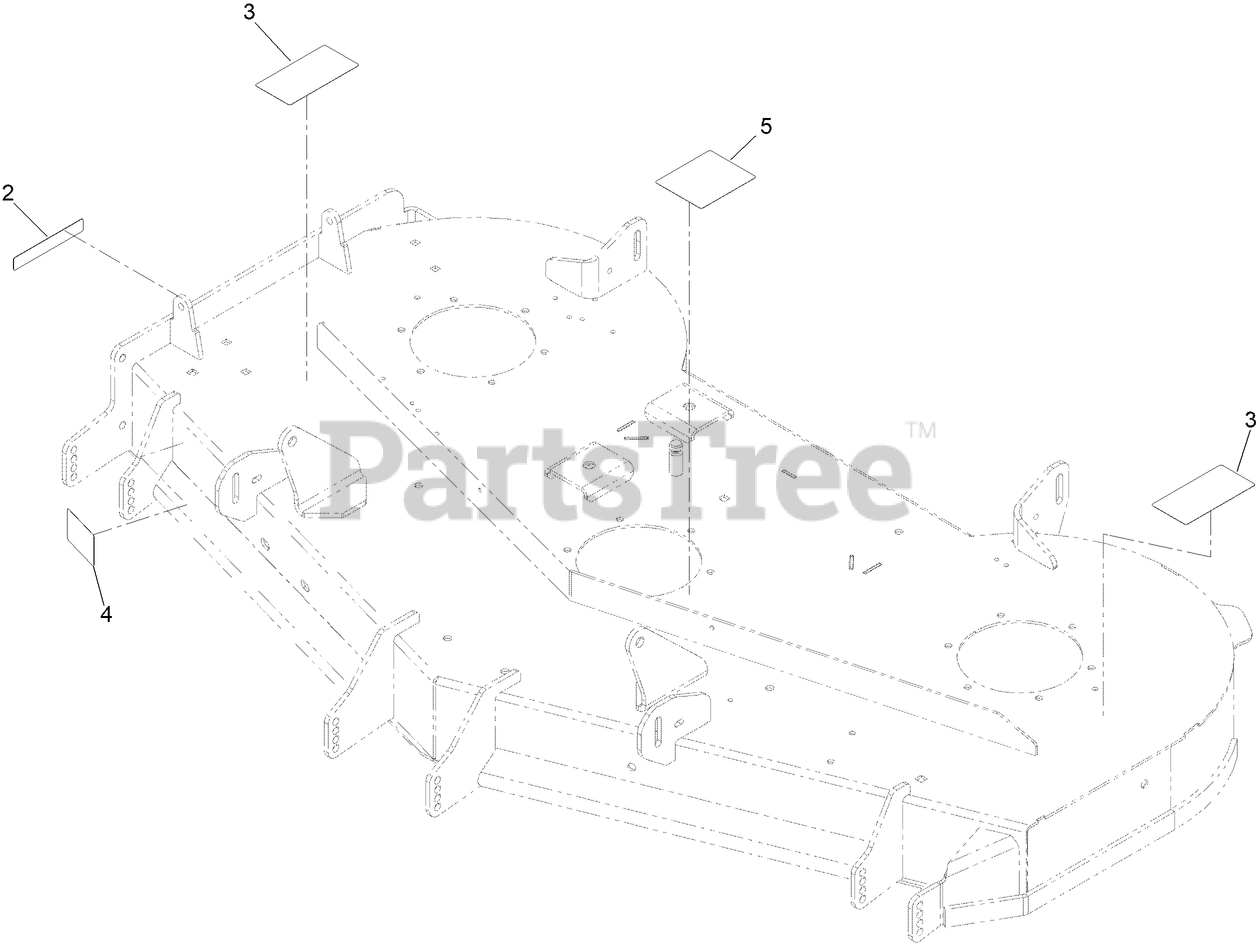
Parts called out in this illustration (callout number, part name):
2	DECAL-DANGER
3	DECAL-DANGER, DECK
4	DECAL-SCALP, ANTI
5	DECAL-ROUTING, BELT
